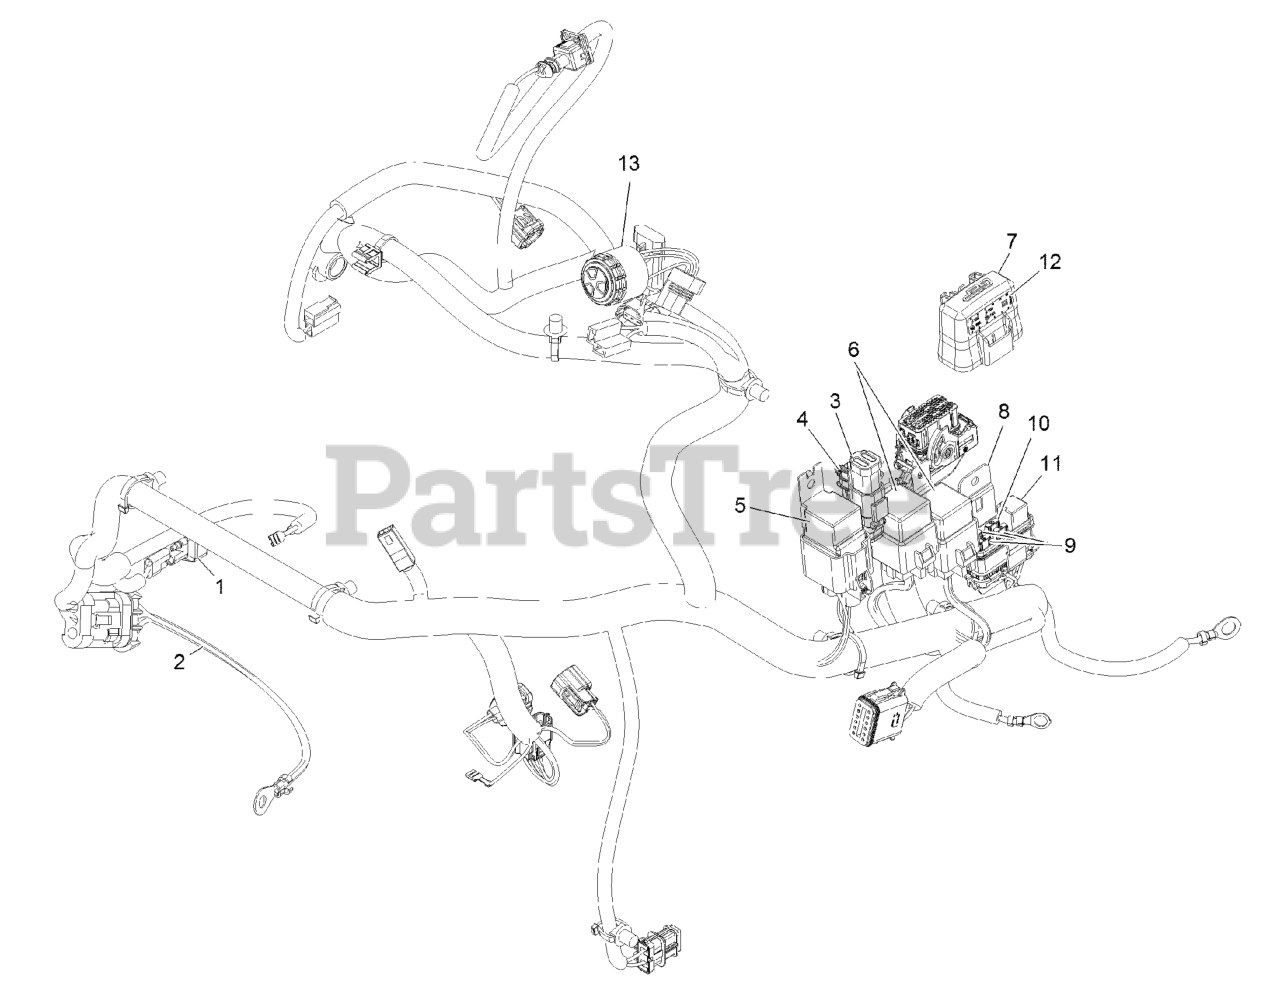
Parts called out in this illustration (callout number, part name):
2	HARNESS-WIRE, FUSIBLE LIN
3	Connector (6M)
4	CLIP-CONNECTOR
5	RELAY-70A
6	RELAY-MINI
7	COVER-BLOCK, FUSE
8	CLIP-MOUNTING
9	FUSE-MINI BLADE, 15 AMP
10	FUSE-MINI BLADE, 10 AMP
11	RELAY-MICRO
12	DECAL-FUSE
13	ALARM-DUAL TONE
